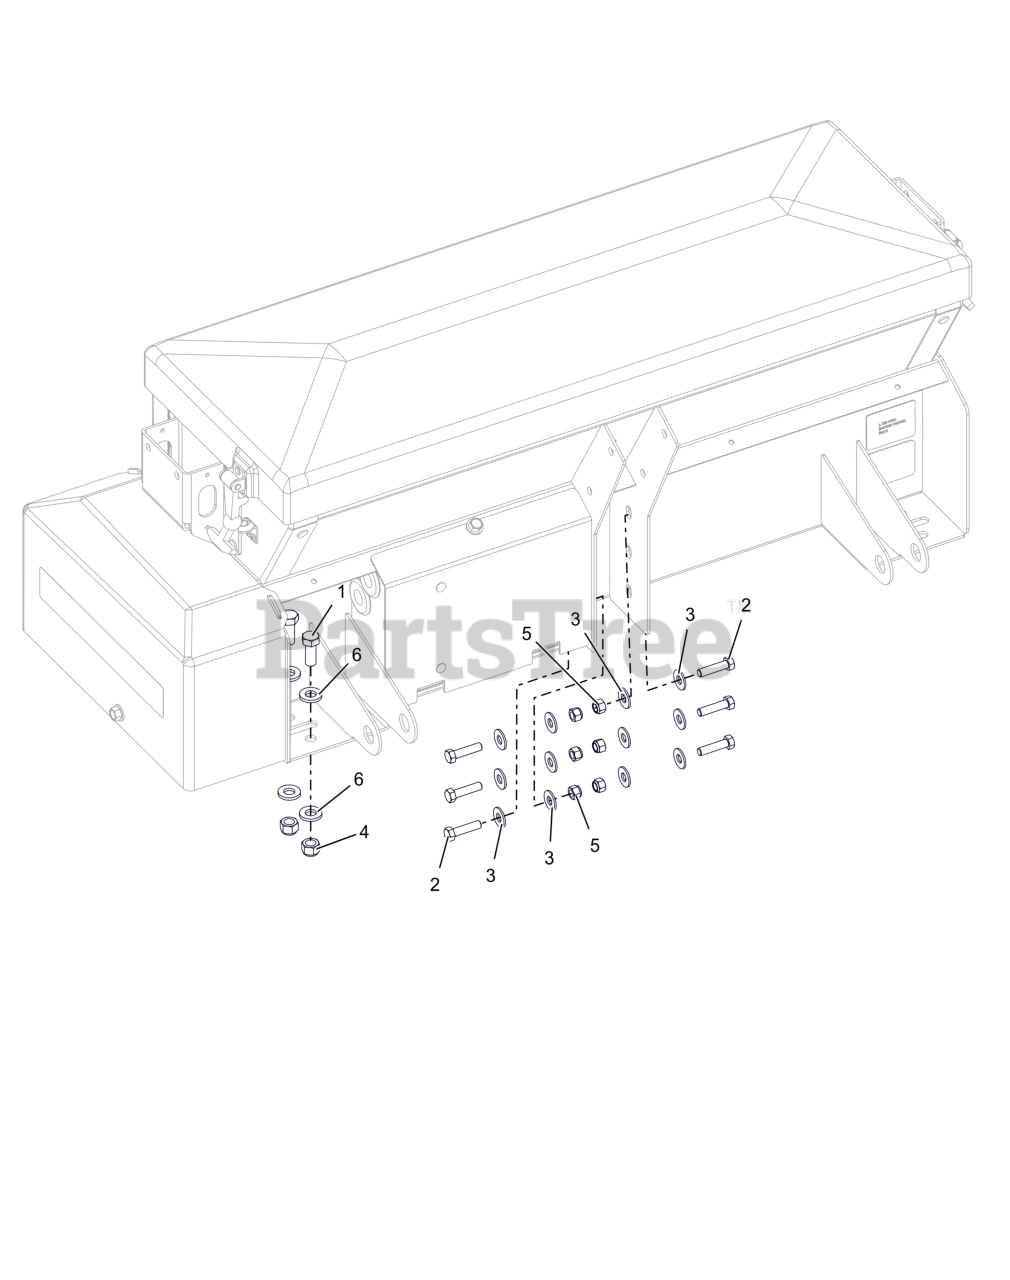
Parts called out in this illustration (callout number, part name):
1	BLT,HEX .50-13X1.25 G5 ZCC
2	BLT, HEX .38-16X1.50 G5 ZCC
3	WSHR,FLT .438X1.00X.083 ZCC
4	NUT,NYL .50-13 G5 ZCC
5	NUT,NYL .38-16 G5 ZCC
6	WSHR, FLAT -SS .531X1.063X.137
